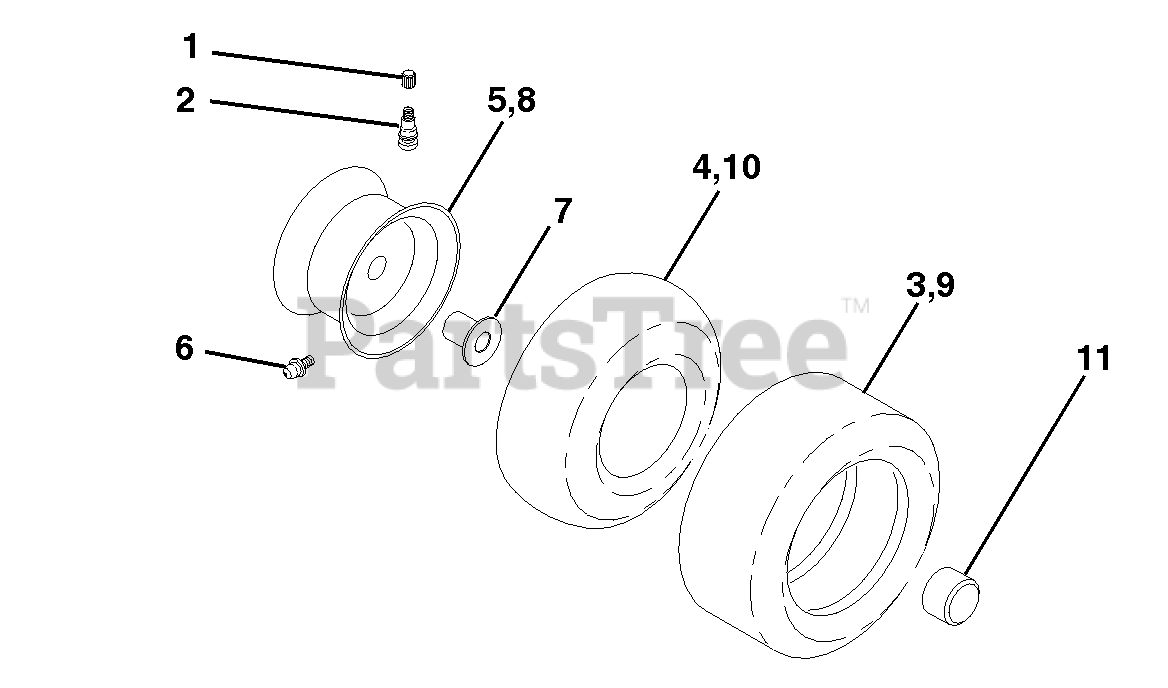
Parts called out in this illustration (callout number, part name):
1	Cap Valve Tire
2	Stem Valve
3	Tire F Ts 15 X 6.0 - 6 Service
4	Tube Front
5	Rim Asm 6" front Silver Service
6	Fitting Grease
7	Bearing Flange
8	Rim Asm 8" rear Silver Service
9	Tire R Ts 20 x 10-8 C Service
10	Tube Rear
11	Cap Axle Blk 1 50 X 1 00
